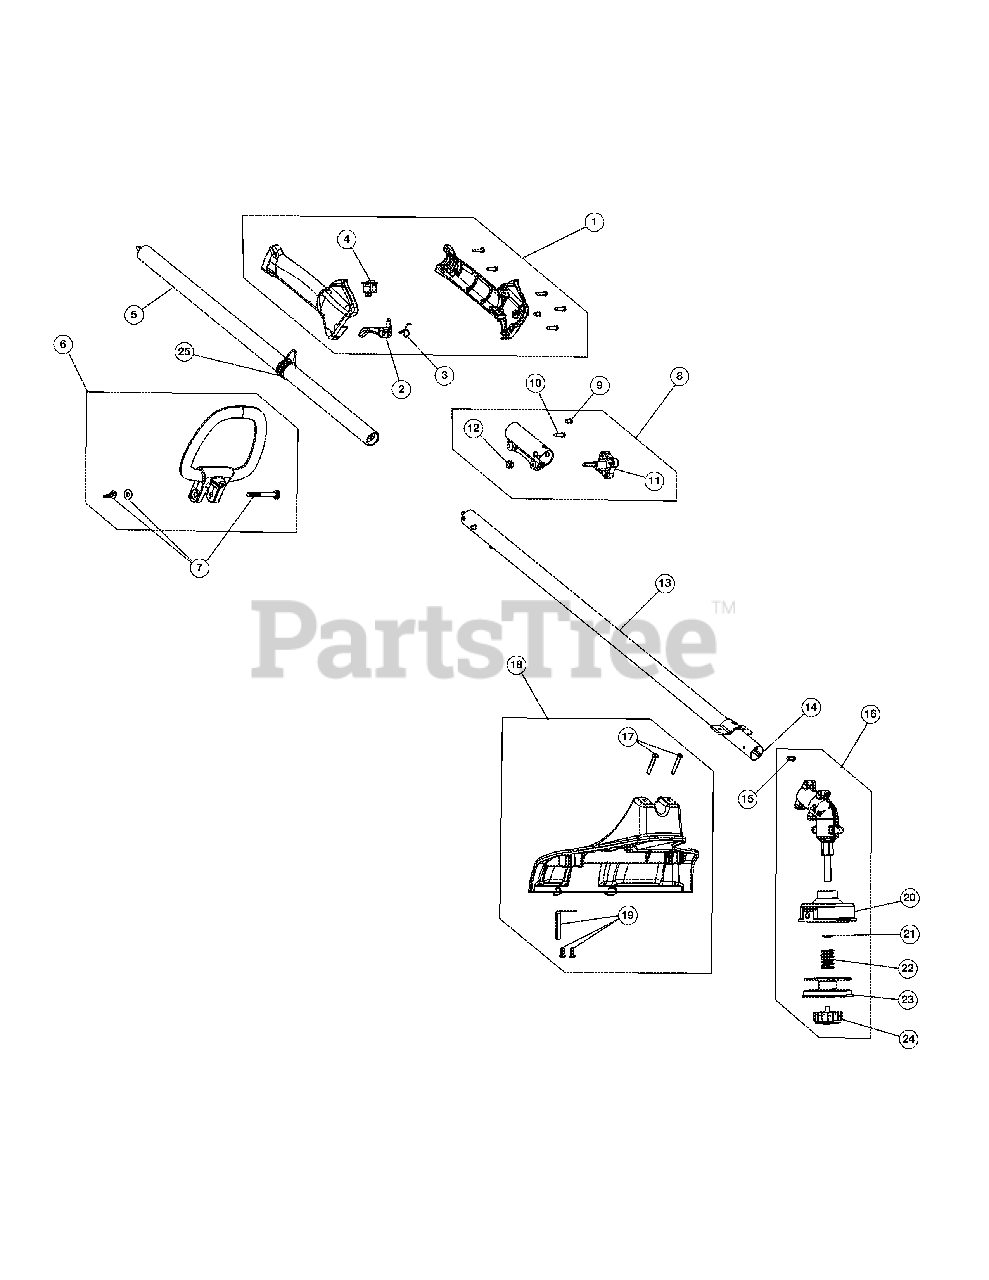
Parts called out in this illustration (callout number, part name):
1	Throttle Housing Assembly (Incl Ref No. 2-4)
2	Throttle Trigger
3	Throttle Trigger Spring
5	Upper Drive Shaft Housing Assembly
6	D-Handle Assembly (Incl Ref No. 7)
7	D-Handle Hardware
8	Split Boom Coupler (Incl Ref No. 9-12)
11	Adjustment Knob (Incl Ref No. 12)
12	Knob Retaining Nut
13	Lower Drive Shaft Housing Assembly
14	Lower Flexible Drive Shaft
15	Anti-Rotation Screw
16	Gear Box Assembly (Incl Ref No. 15 & 20-24)
17	Shield Mounting Screws
18	Shield Assembly (Incl Ref No. 17 & 19)
19	Blade Assembly
20	Outer Spool Assembly (Incl Ref No. 21)
21	Retainer
23	Inner Reel
24	Bump Knob Assembly
25	Shoulder Strap Clip
